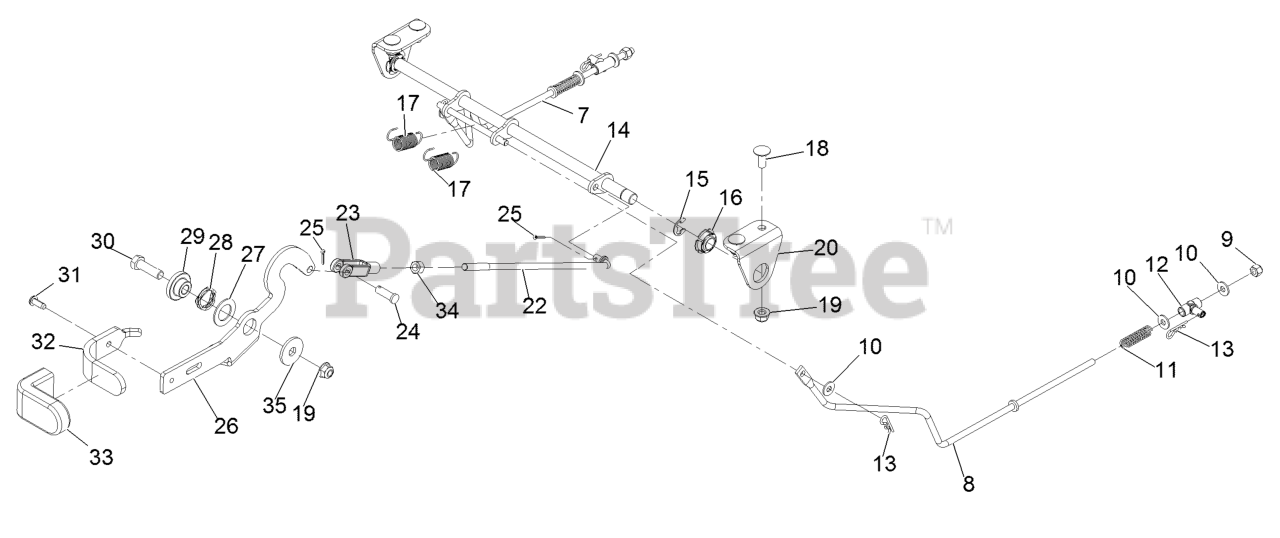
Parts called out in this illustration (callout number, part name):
7	ROD-BRAKE, RH
8	ROD-BRAKE, LH
9	NUT-LOCK, NI
11	SPRING-COMPRESSION
12	MOUNT-PIVOT
14	PIVOT-BRAKE
15	RING-RETAINING, EXTERNAL
16	BEARING-SPHERICAL
17	SPRING-EXTENSION
18	SCREW-CARR
19	NUT-HF, NI
20	ANGLE-MOUNT PIVOT
22	ROD-LINK HANDLE
23	YOKE-ADJUSTABLE
24	PIN-CLEVIS
25	PIN-COTTER
26	LEVER-BRAKE
27	WASHER-THRUST
28	WASHER-WAVE
29	PIVOT-FLANGE
30	SCREW-HH
32	HANDLE-BRAKE
33	GRIP-LEVER
34	NUT-HEX
35	WASHER
